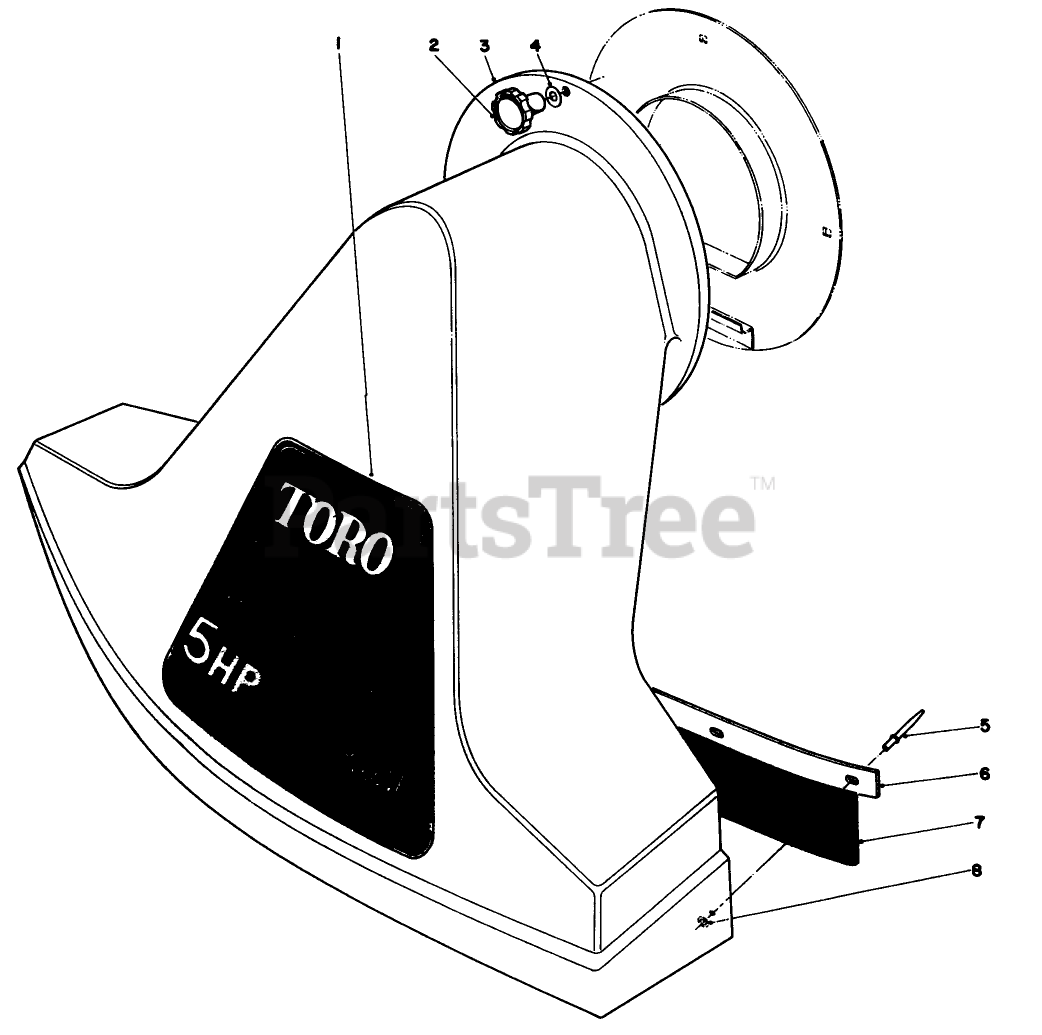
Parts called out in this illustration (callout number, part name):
3	SNOUT ASM
5	POP RIVET 3/16X.375LG
7	FLAP-RUBBER
8	WASHER-FLAT
